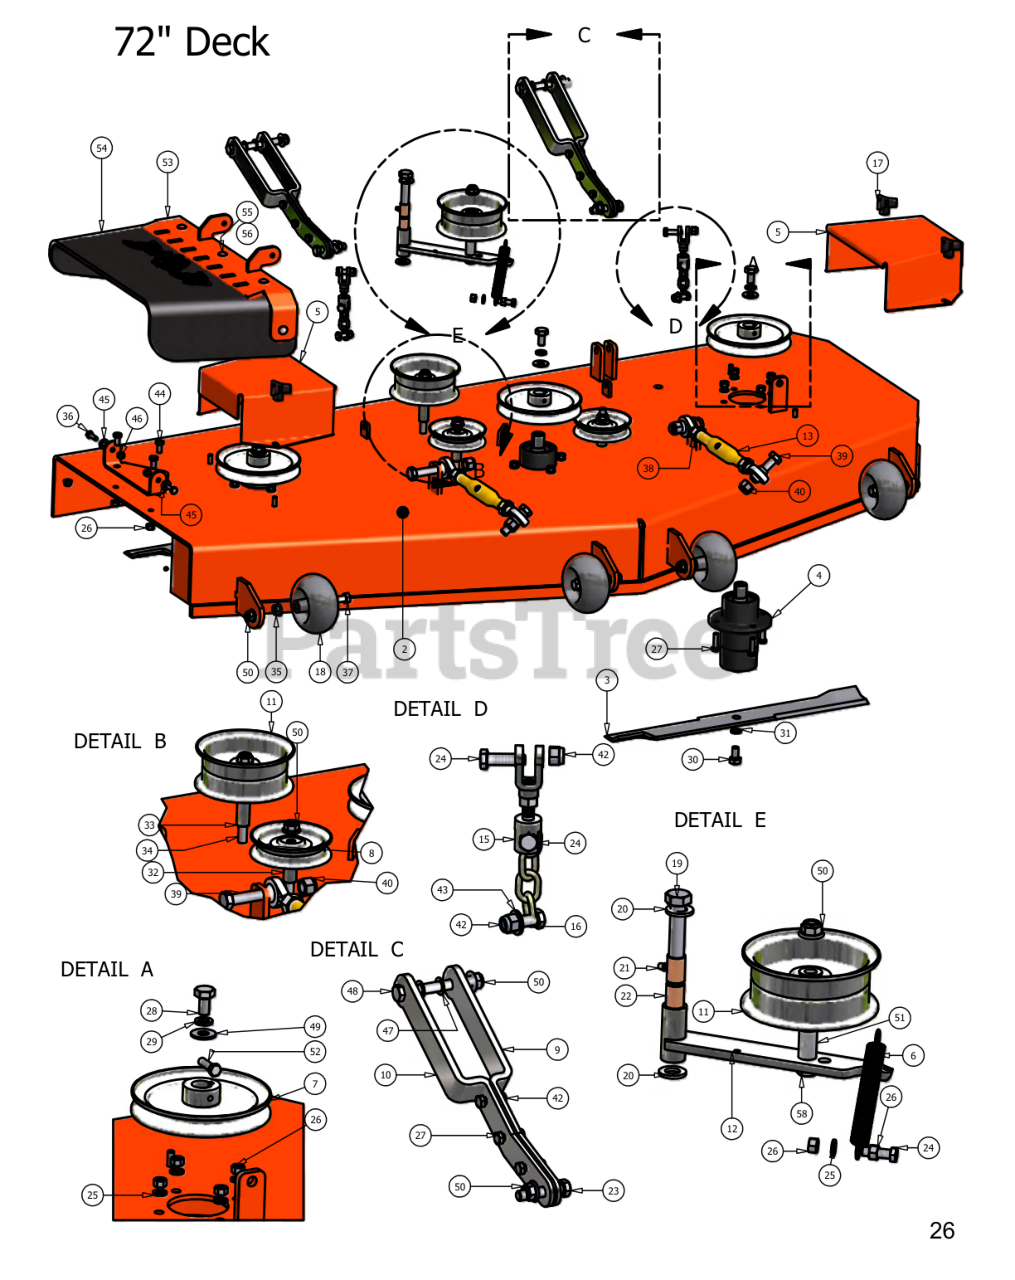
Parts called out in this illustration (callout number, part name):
1	72" Deck Belt-B189
3	72" Fusion Blade
5	Pulley Guard
6	Deck Idler Spring
7	7" Deck Pulley
8	4 3/4" Idler Pulley
9	Deck Support Arm (Right)
10	Deck Support Arm (Left)
11	5/3/4" Flat Idler Pulley
12	Deck Idler Arm
13	Turnbuckle (Toplink)
14	Female Yoke
17	5/16" Knob
18	Anti-Scalp Rollers
19	5/8" x 4" Hex Bolt
20	.635 ID Plastic Washer
21	Grease Fitting (Drive-In Type
22	5/8" ID x 1 1/8" Brass Bushing
23	1/2" x 2 1/2" Hex Bolt
24	3/8" x 1 1/2" Hex Bolt
25	3/8" Lock Washer
26	3/8" Hex Nut
27	3/8" x 1 1/4" Hex Bolt
28	1/2" x 1 1/2" Fien Threas Bolt
29	1/2" Lock Washer
30	5/8" x 1.5" Fine Threaded Bolt
31	5/8" Lock Washer
32	1 1/2" Pulley Spacer
33	1 3/4" Pulley Spacer
34	1/2" x 3 1/2" Bolt
35	1/2" Flange Nut
36	5/16" x 1" Hex Bolt
37	1/2" x 4" Bolt (Grade 8)
38	3/4" Left Handed Nut
39	5/8" x 2 1/2" Hex Bolt
40	5/8" Nylock Nut
41	3/8" Fine Threaded Jam Nut
42	3/8" Nylock Nut
43	3/8" Flat Washer
44	3/8" x 3/4" Hex Bolt
45	.360 ID Plastic Washer
46	5/16" Nylock Nut
47	1/2" Brass Washer
48	1/2" x 4 1/2" Bolt
49	1/2" Cupped Washer
50	1/2" Flange Lock Nut
51	1 1/4" Pulley Spacer
52	3/8" Set Screw
53	2007Hanger Plate
54	Rubber Side Discharge
55	5/16" x 1 1/2" Carriage Bolt
56	5/16" Flange Nut
57	2007 Lower Hanger Plate
